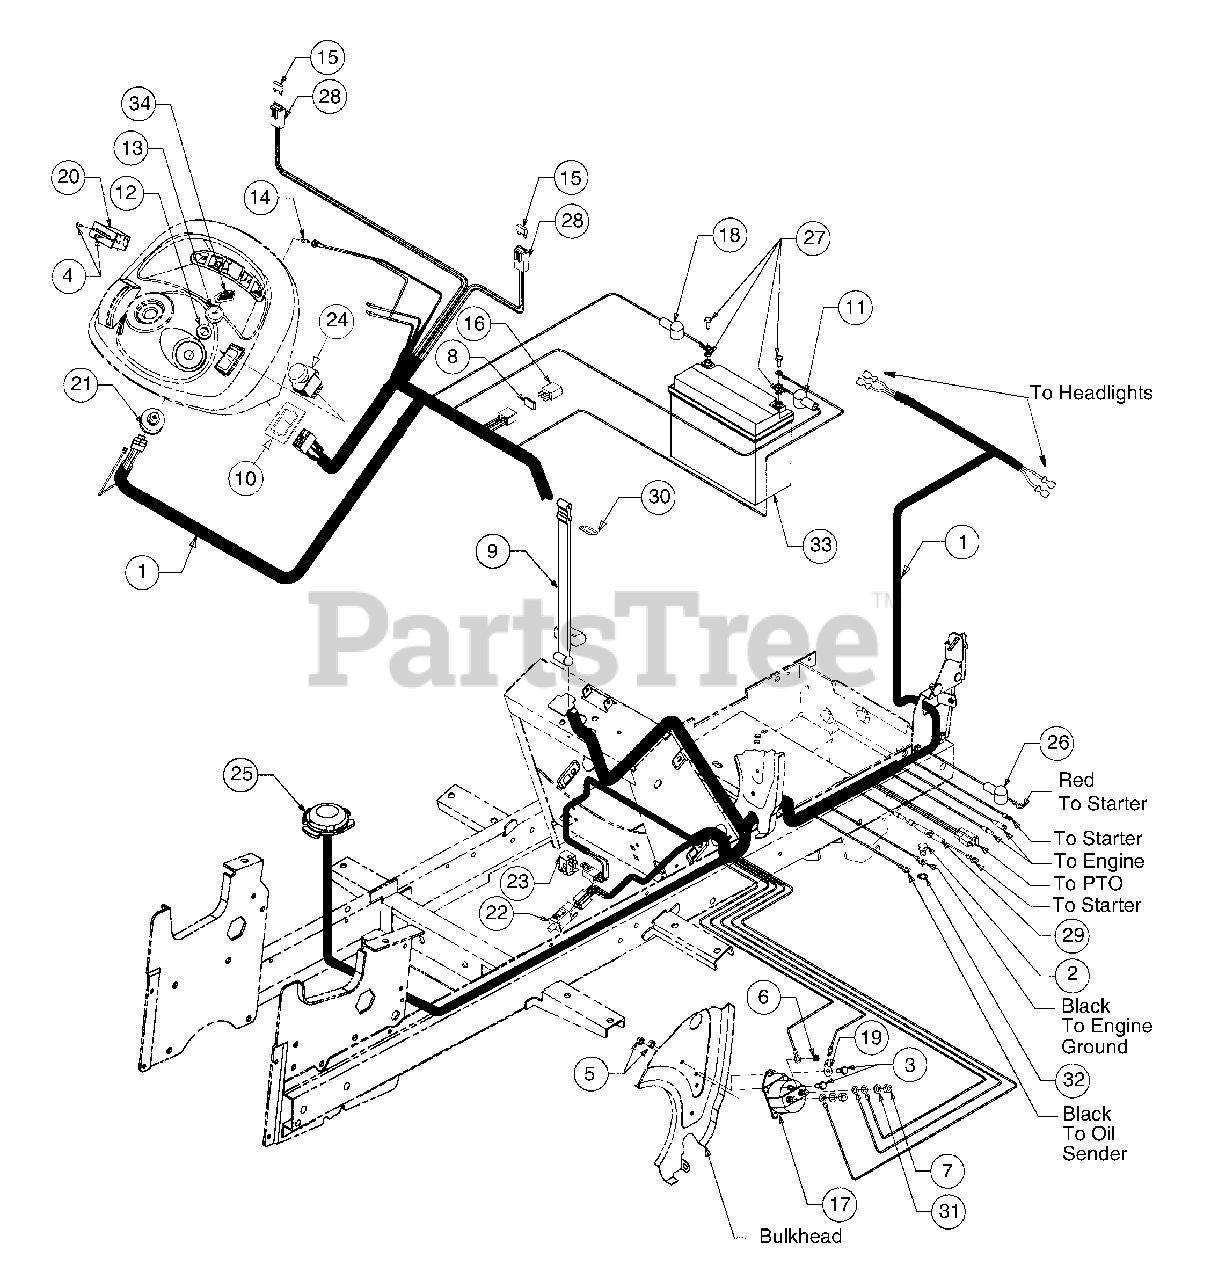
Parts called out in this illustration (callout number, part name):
1	Wire Harness, Main
2	Screw, Hex Cap, 3/8-16 x .50
3	Screw, Hex Cap, 1/4-20 x .625
4	Screw, Truss Hd Tapp, #6 x .62
5	Nut, Hex Sems, 1/4-20
6	Nut, Hex, #10-32
7	Nut, Hex, 5/16-18 GR5
8	Gasket, Silicone
9	Strap, Battery Retainer
10	Bracket, PTO Switch Retainer
11	Cover, Terminal Black
12	Nut, Ignition Switch
13	Cap, Ignition Switch
14	Bulb, Indicator
15	Fuse, 25 Amp
16	Relay
17	Solenoid, Starter
18	Cover, Terminal Red
19	Lug, Quick Connect
20	Hour Meter
21	Switch, Ignition
22	Switch, Interlock (Brake)
23	Switch, Snap Mount - Normally Closed
24	Switch, PTO
25	Switch, Seat
26	Cover, Terminal Red
27	Battery Cable Hardware
28	Holder, Fuse w/Mounting Clip
29	Diode Assembly w/Lead
30	Hook, Wire Rectangular
31	Washer, Lock, 5/16
32	Washer, External Lock, 3/8
33	Battery
34	Key, Ignition
